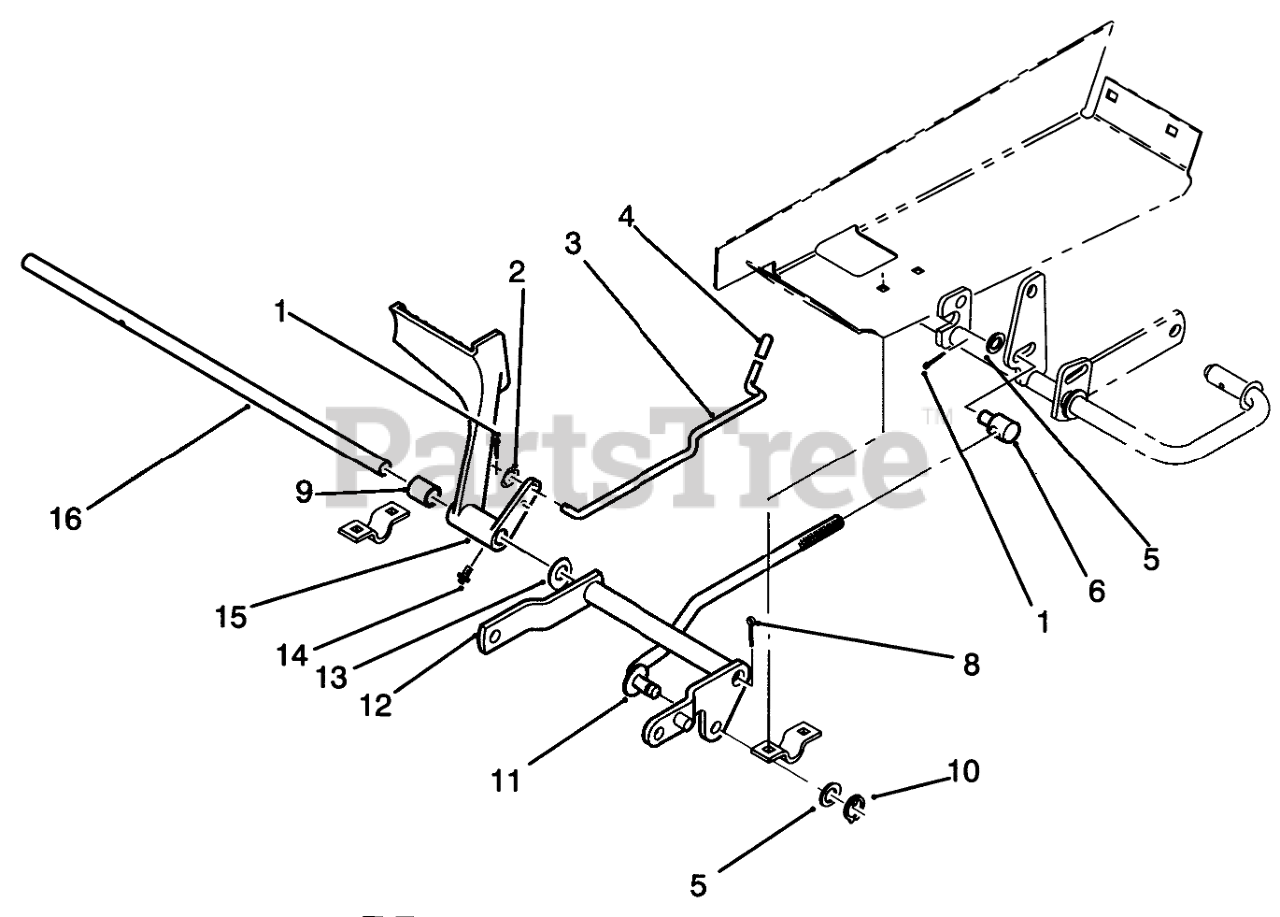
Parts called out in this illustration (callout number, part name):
1	PIN-COTTER
2	WASHER-PLAIN
3	ROD-BRAKE LOCK
5	WASHER-FLAT
6	ROD-TRUNNION LIFT
8	PIN-COTTER
9	SPACER
10	RING-RETAINING, EXTERNAL
12	Arm
13	Washer
14	FITTING-GREASE
15	Pedal-Brake
16	SHAFT
